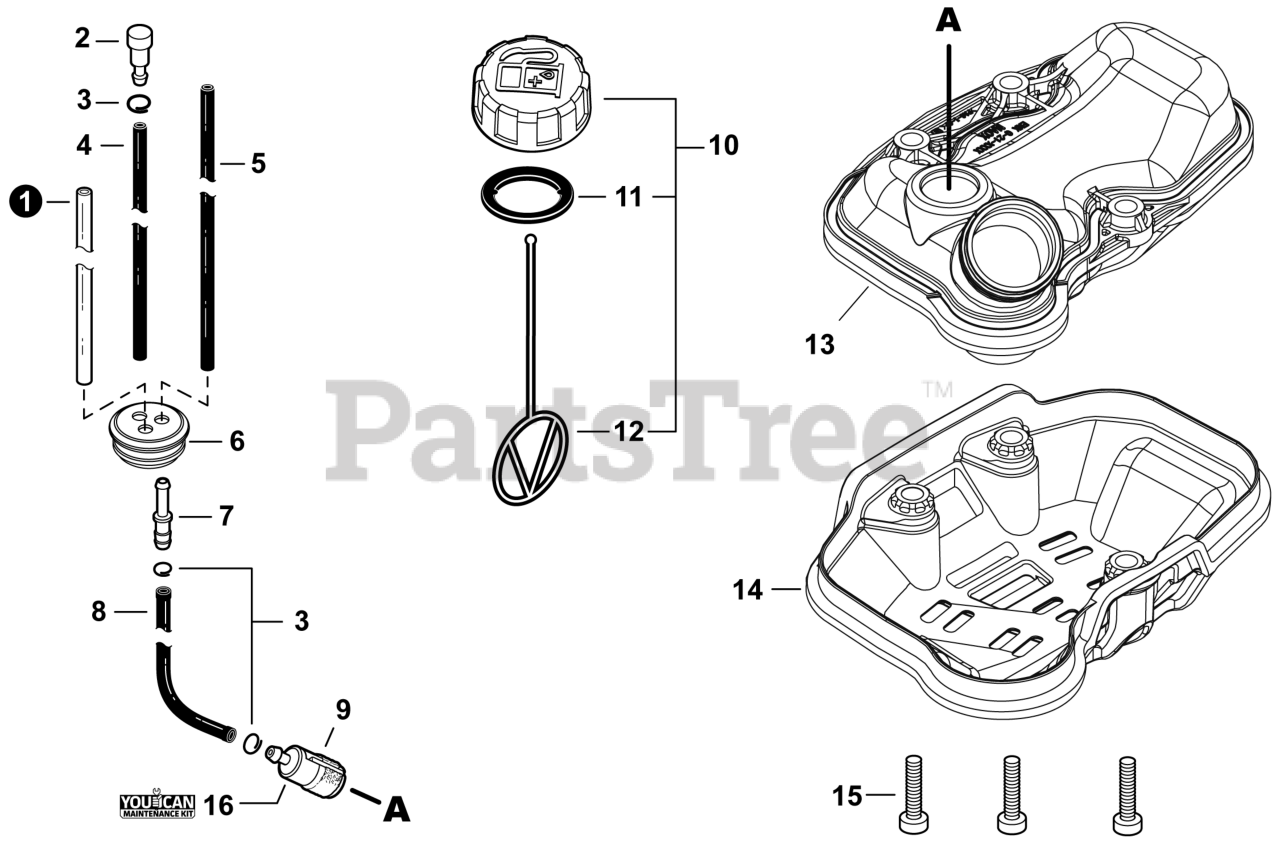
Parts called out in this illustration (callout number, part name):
1	PIPE, FUEL 3x6x85 YELLOW
2	VENT ASSY
4	PIPE, FUEL 3x5x90 BLACK
5	PIPE, FUEL 3x5.5x78 BLACK
6	GROMMET, FUEL
7	CONNECTOR, PIPE 5x3.5
8	PIPE, FUEL 3x5x105 BLACK
9	FILTER, FUEL
10	CAP ASSY, FUEL
11	GASKET, FUEL CAP
12	CONNECTOR, CAP L= 123
13	TANK, FUEL
14	GUARD, FUEL TANK
15	BOLT, TORX 5x25
16	TUNE-UP KIT - YOUCAN™
